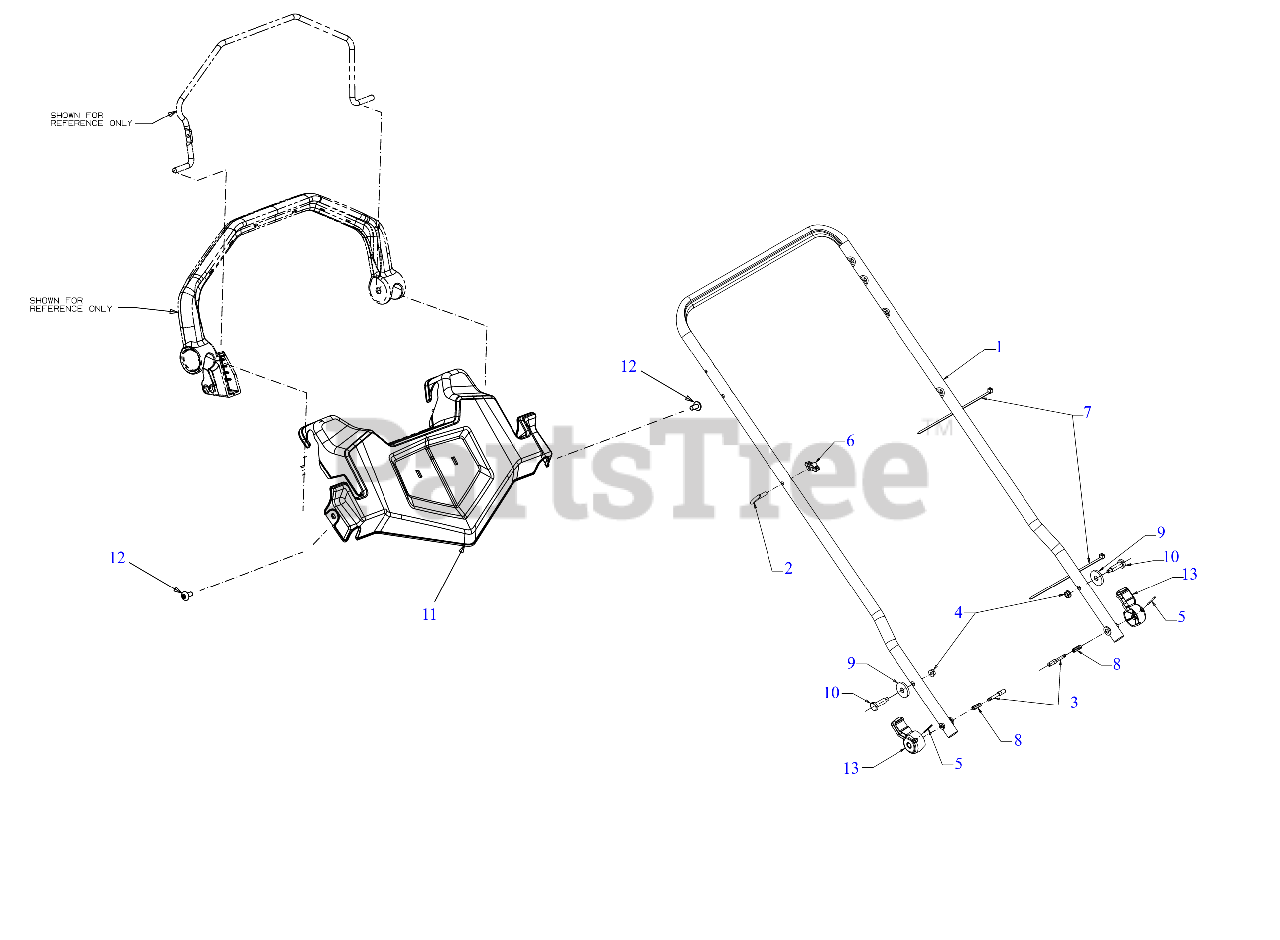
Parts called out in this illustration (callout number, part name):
1	23" HANDLE ASSEMBLY
2	EYEBOLT 1/4-20
3	HANDLE ADJUSTMENT PIN
4	LOCK NUT 1/4
5	SPLIT ROLL PIN 5/64 x 1.38
6	HANDLE KNOB
7	7" CABLE TIE
8	COMPRESSION SPRING
9	FLAT WASHER
10	SHOULDER SCREW
11	HANDLE CONSOLE
12	SCREW 1/4-14 x .625
13	LEVER KNOB (SBD GRAY)
